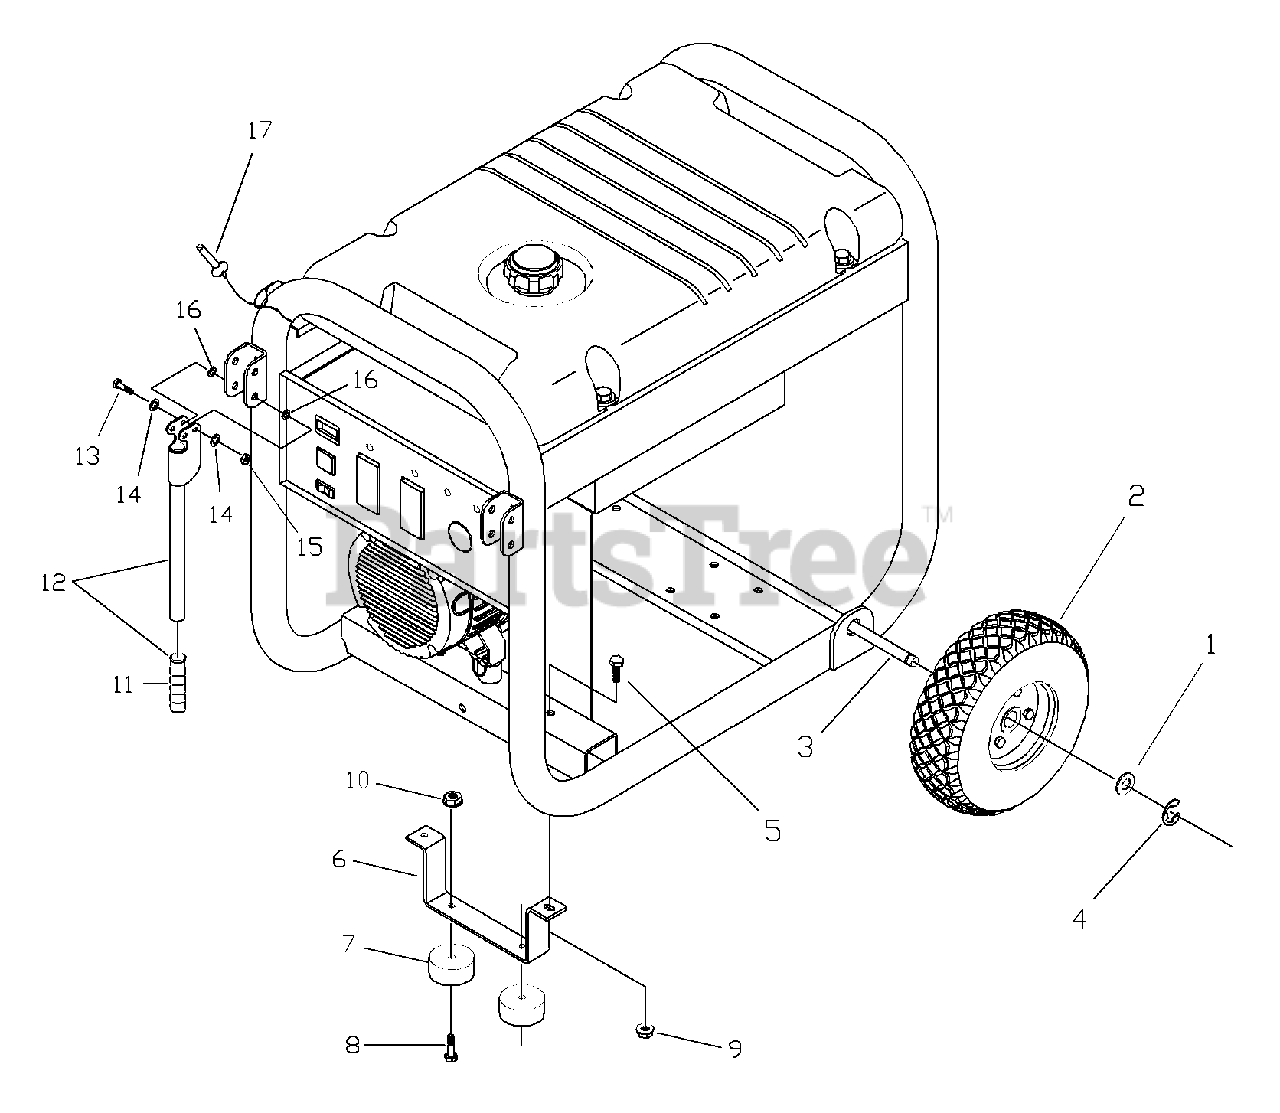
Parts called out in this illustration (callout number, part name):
6	BRACKET, Support, Unit
7	MOUNT,Vibe Donut Type
10	NUT, Lock
11	GRIP, Handle
12	ASSY, Handle
15	NUT, Nylok
16	WASHER, Nylon
17	PIN, with Lanyard
